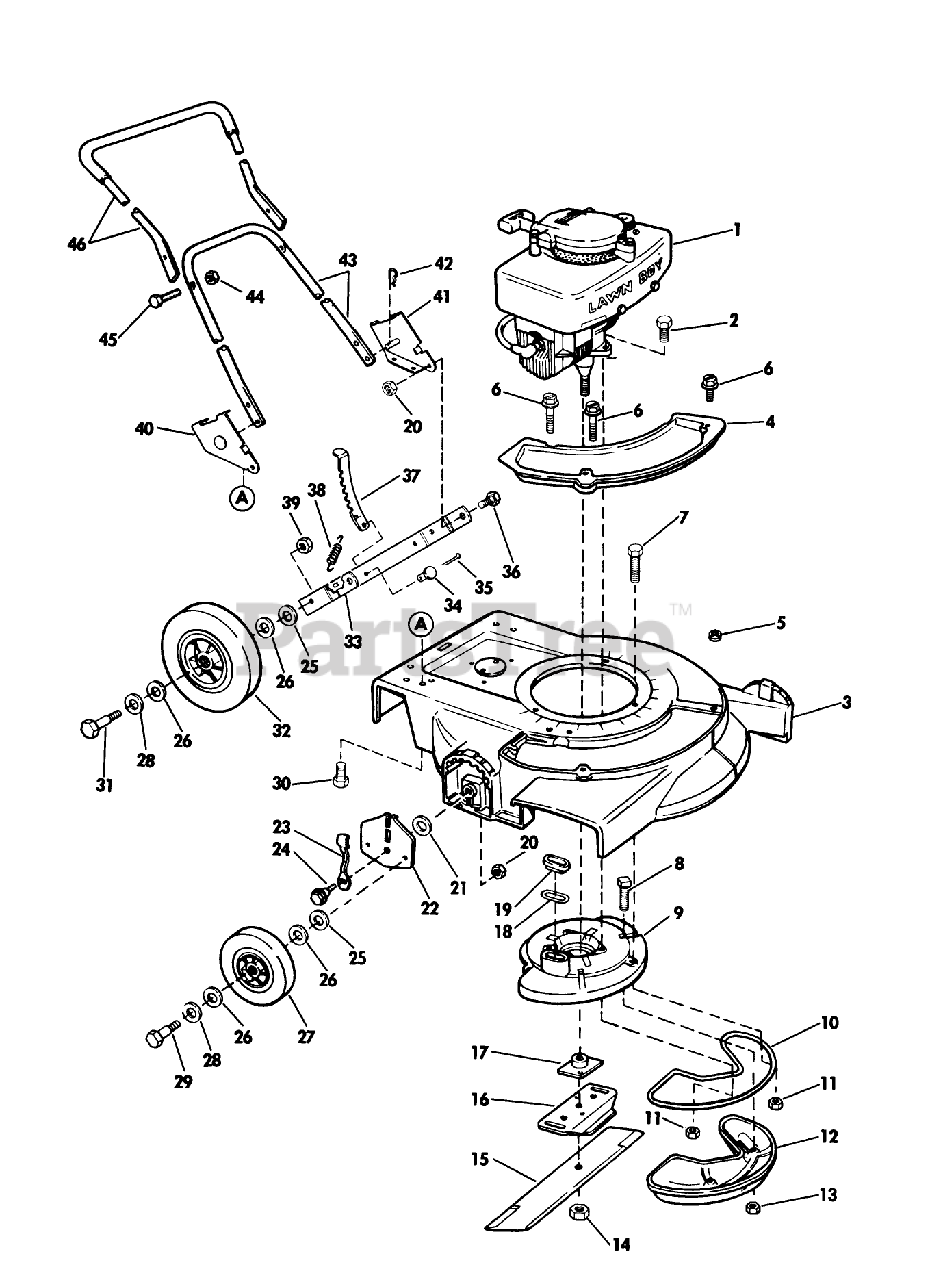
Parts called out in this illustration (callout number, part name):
1	Engine-Model C-18
6	SCREW SEMS TRM HEX HD
13	LOCKNUT E
14	NUT-BLADE
17	PLATE AND COLLAR ASM
18	GASKET S
25	WASHER WROUGHT
29	BOLT WHEEL
36	BOLT-SHOULDER
38	SPRING N.A.S
39	LOCKNUT
42	HAIR PIN
